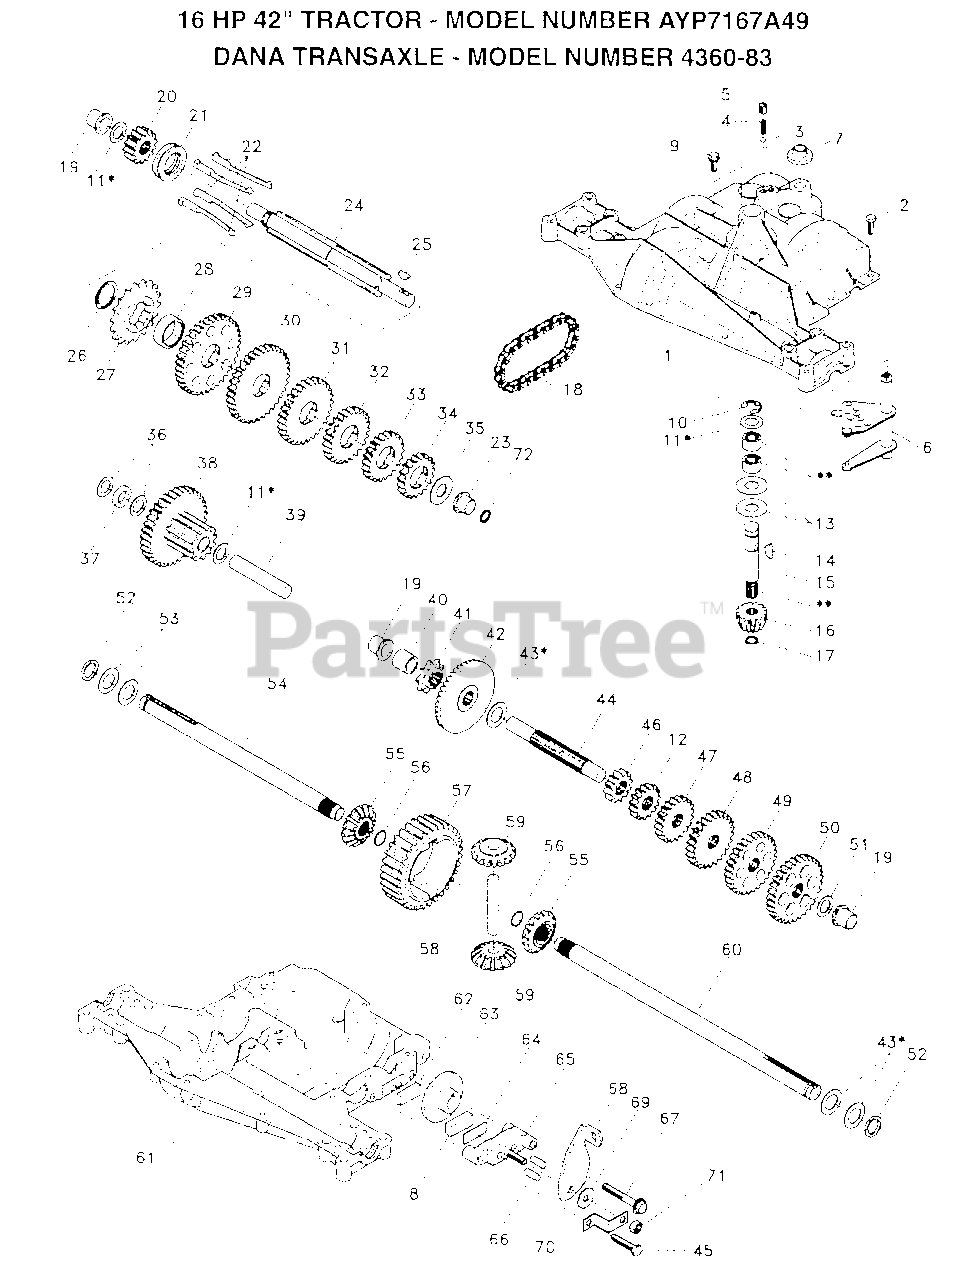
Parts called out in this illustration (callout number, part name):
1	HOUSING UPPER TRN
4	"SPRING, DETENT LT"
5	"SCREW, SET LT"
6	SHIFTER.ASM.KIT.
7	SHIFTER BOOT
8	PUCK T
9	SCREW TAP W/SEAL
11	ASM KIT SHIM 4689
12	GEAR SPUR 15 TTH
13	WASHER T
14	KEY WOODRUFF-DANA
17	"RING,RETAINING LT"
18	"CHAIN,24 PTCH LT"
19	BEARING.FLNG.5510
20	GEAR SPUR 14 TTH
21	COLLAR CLUTCH
22	KIT.ASM.CLTCH KEY
24	SHAFT INTER 5404
25	WOODRUFF KEY
26	"RING,RETAINING LT"
27	SPROCKET 18T T
28	SPACER YT
29	GEAR SPUR 37 TTH
30	GEAR SPUR 35 TTH
32	GEAR 25T LT
33	GEAR SPUR 22 TT
34	SPUR GEAR 19T
35	"WASHER, PLAIN LT"
36	WASHER 025
37	SPACER
38	ASSM GEAR COMB
39	SHAFT IDLER
40	SPACER T
41	SPROCKET 9T LT
43	ASM KIT SHIM
44	SHAFT T
45	"SCREW, TAPPING LT"
46	GEAR SPUR 12 TTH
48	"GEAR, SPUR 25T LT"
49	GEAR 28T T
50	"GEAR, SPUR 31T LT"
51	WASHER 060
52	NEOPRENE WASHER
53	WASHER 031
55	GEAR LT
56	"RING,RETAINING LT"
58	SHAFT T
59	"GEAR,MITER 15T YT"
61	HOUSING LOWER TNS
62	PUCK T
63	BRAKE DISC. T
64	SPACER LT
66	PIN T
69	WASHER LT
71	NUT.LOCK.5/16-24
72	SEAL OIL DANA5416
